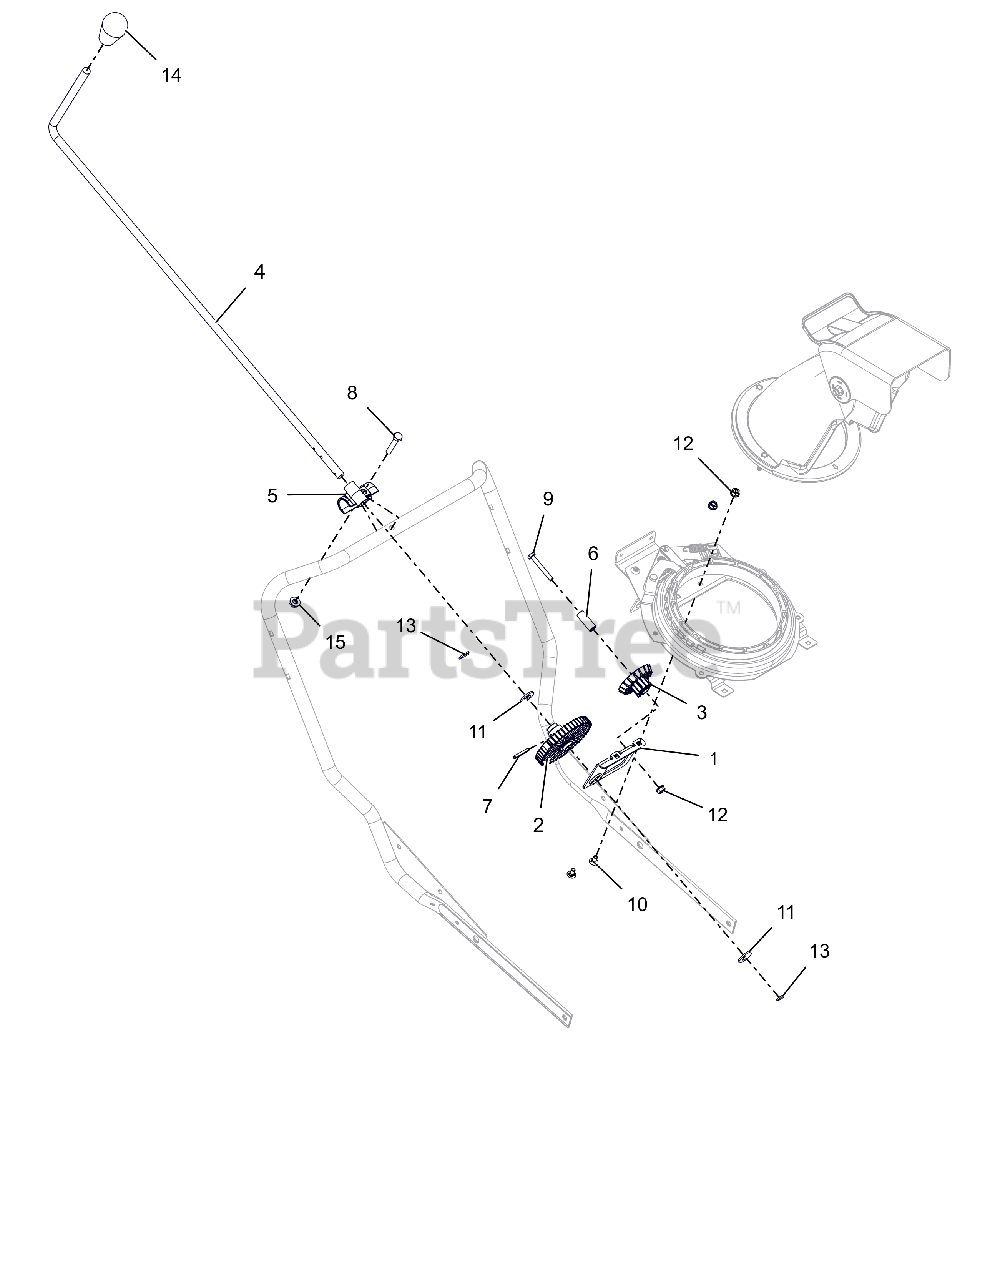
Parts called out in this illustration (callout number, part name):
1	BRKT, CHUTE ROTATION - FRONT
2	GEAR, ROTATION - REMOTE SPUR
3	GEAR, ROTATION - REMOTE COMBO
4	ROD, ROTATION - CHUTE
5	ROD, ROTATION - HOLDER
6	BSHG,SLV - .265 X .505 X 1.341
7	PIN-ROLL .188X1.25
8	@BLT-HEX .31-18X1.75 GR5 YWZC
9	@BLT-HEX .25-20X2.00 GR5 YWZC
10	@BLT-RDHDSQNK .25-20X.50 G5YZ
11	@WSHR-FL-STL.531X1.06X.095YWZC
12	@NUT-LK-TOP-FLG .25-20 YWZC
13	CLIP, SPRING
14	KNOB,SOFT-TEARDROP,PUSH-ON BLK
15	@NUT-LK-TOP-FLG .31-18 YWZC
